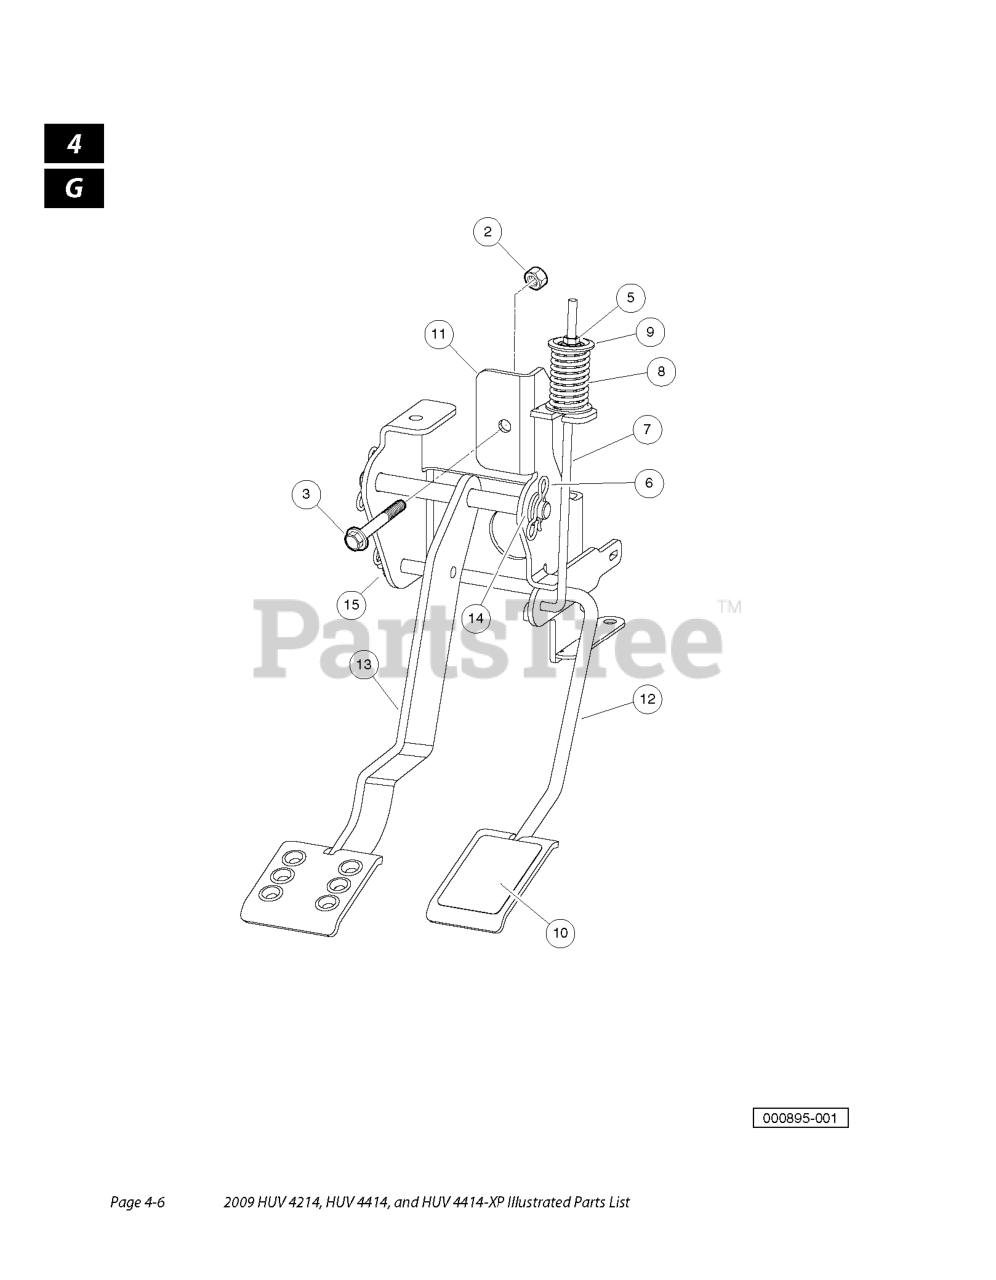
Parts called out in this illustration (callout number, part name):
2	NUT FLG, M8 X 1.25 MECH DEF
3	BOLT, FLG, M8 X X 60
5	NUT-M6X1.0 FLNG ALL MTL LOCK
6	PIN, BOW TIE LOCKING
14	WASHER, M12 HARD
15	WASHER, M10 HARD
